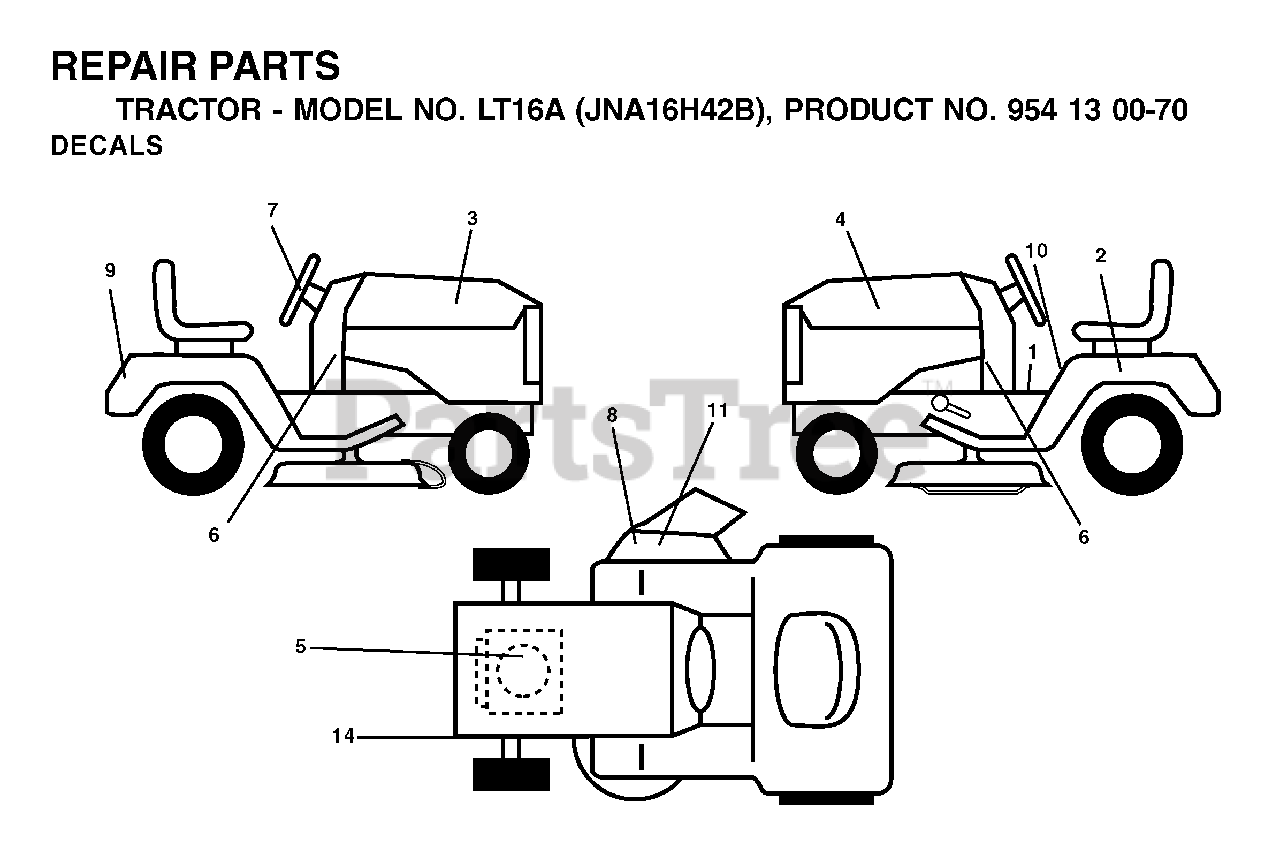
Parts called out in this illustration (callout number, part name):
1	DECAL SET
2	DECAL BTRY SYMBOLS
8	DECAL.WARN.KEEP.HAND.AWAY
10	DECAL FENDER DANGER
11	DECAL DECK "B" 42"
14	DECAL V BELT SCHEMATIC
